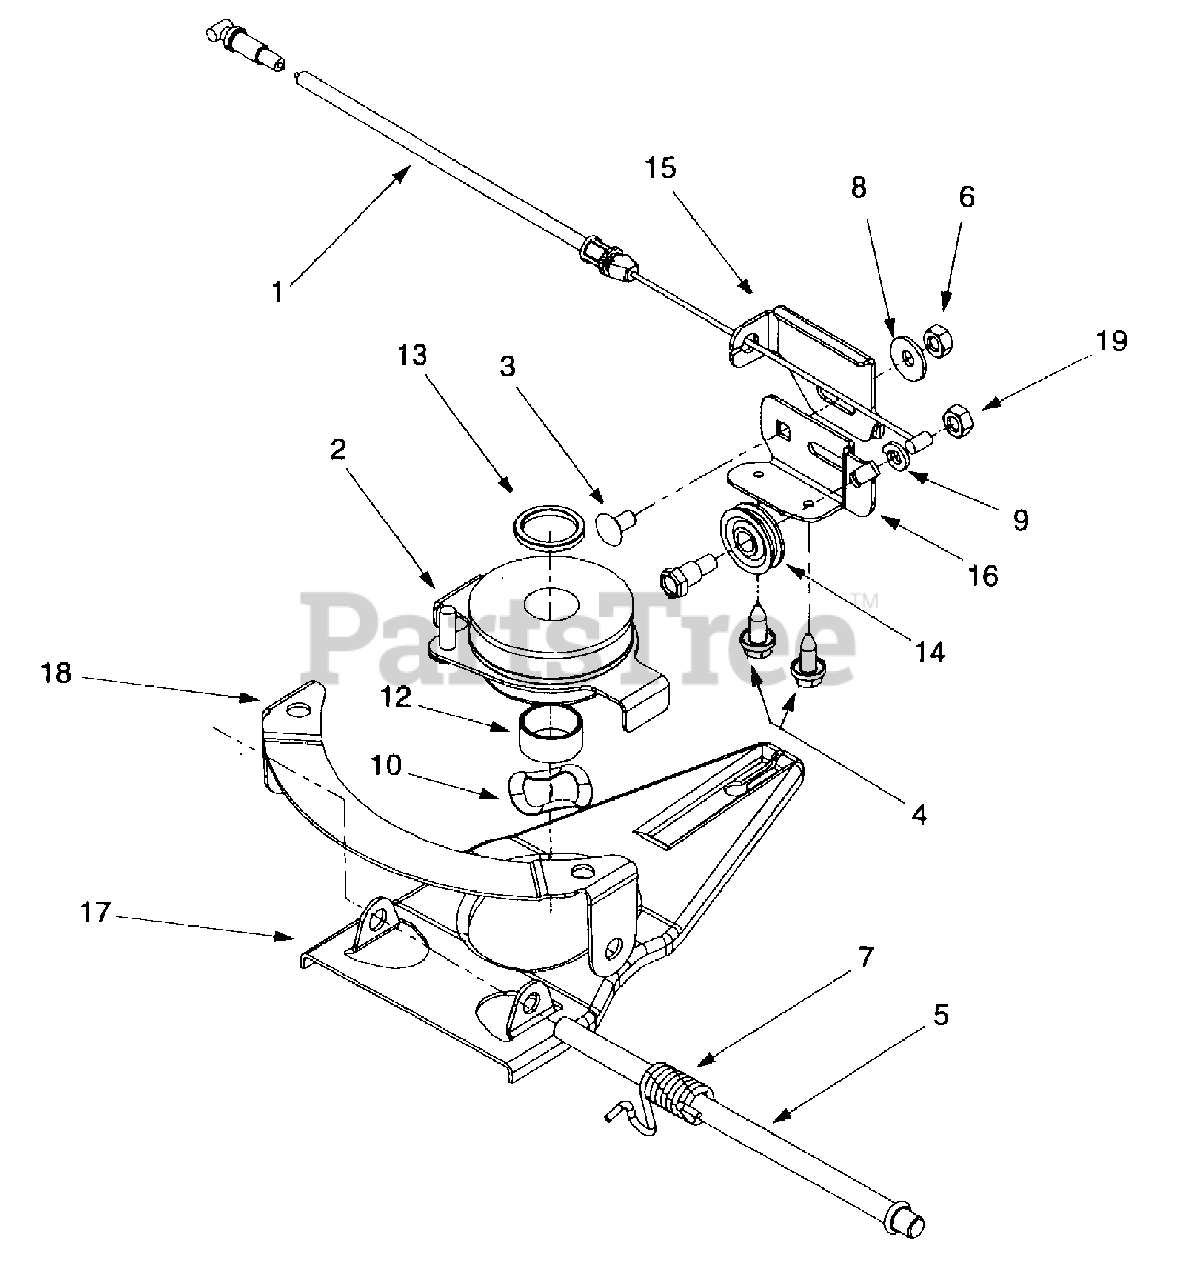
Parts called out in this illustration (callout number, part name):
1	Speed Selector Cable, 53"
2	Multi-speed Pulley Assembly
3	Carriage Bolt, 1/4-20 x .5
4	Self-tapping Screw, 1/4-20 x .625
5	Pivot Shaft
6	Nut, 1/4-20
7	LH Torsion Spring
8	Bell Washer, .265 x .75 x .062
9	Lock Washer, 1/4
10	Wave Washer, 1.38 x .88 x .029
12	Sleeve Spacer, .88 ID x 1 OD x .48
13	Sleeve Spacer, .88 ID x 1.13 OD x .12
14	Cable Roller
19	Hex Nut, 1/4-20
